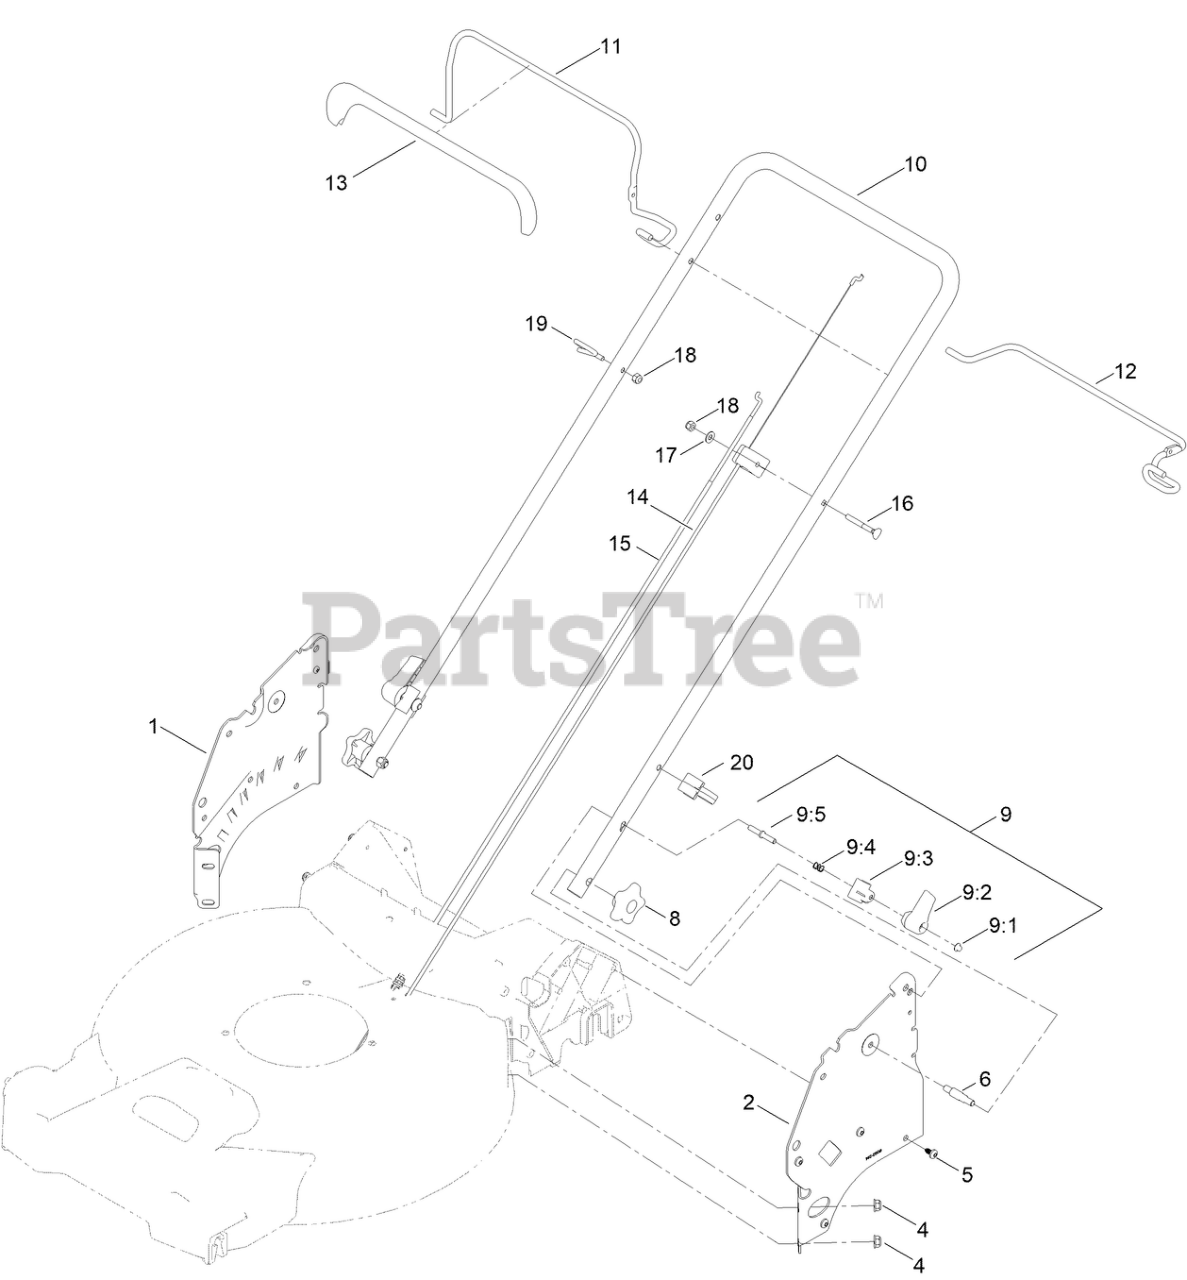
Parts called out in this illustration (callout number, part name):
1	PLATE-HANDLE, RH
2	PLATE-HANDLE, LH
4	NUT-HF
5	SCREW-PLASTIC,PH
6	BOLT-SHOULDER, HANDLE
8	KNOB-HANDLE
9	QUICK RELEASE ASM
9:1	NUT-PUSH
9:2	LEVER-RELEASE
9:3	ANCHOR-SPRING
9:4	SPRING-COMPRESSION
9:5	ROD-RELEASE
10	HANDLE-UPPER
11	BAIL-BRAKE
12	BAIL-TRACTION
13	COVER-BAIL
14	CABLE-BRAKE
15	CABLE-TRACTION
16	SCREW-HANDLE
17	WASHER-FLAT
18	NUT-HEX
19	GUIDE-ROPE
20	GUIDE-CABLE
